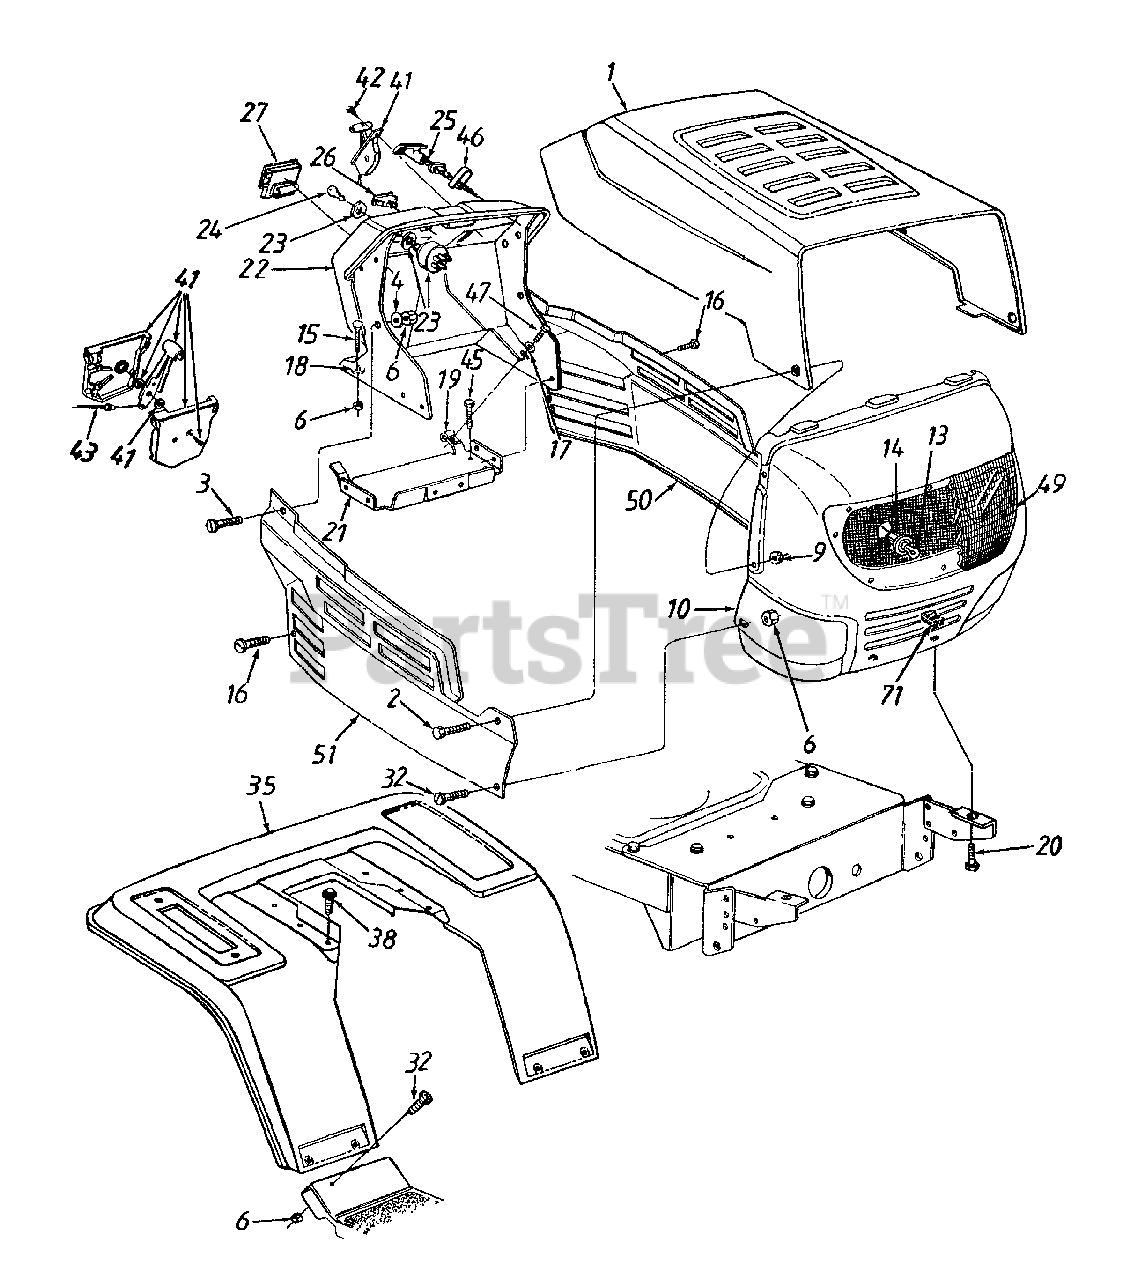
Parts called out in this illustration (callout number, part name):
1	Hood
2	Shld. Bolt .375" Dia. x .125" Lg.
3	Scr. 1/4-20 x .75
4	Wash. .283 x .030
6	Hex Sems Nut 1/4-20 Thd.
9	Flange L-Nut 1/4-20 Thd.
13	Lamp
14	Socket
15	Carriage Bolt 1/4-20 x .75" Lg.
16	Hex Wash. Hd. TT-Tap Scr. 1/4-20 x .5" Lg.
17	Fl-Wash. .281" I.D. x .73" O.D.
18	Bolt Retainer 1/4" I.D.
19	Speed Nut 1/4-20
20	Hex Bolt 5/16-18 x .75" Lg.
23	Ignition Switch
24	Ignition Key
25	Choke Control
26	Light Switch
27	Ammeter
32	Truss Mach. Scr. 1/4-20 x .5" Lg.
38	Hex Wash. Hd. AB-Tap Scr. 5/16 x .75" Lg.
41	Throttle Box Ass'y.
42	Truss Mach. AB-Tap Scr. #10 x .5" Lg.
43	Throttle Control Wire
45	Hex Wash. Hd. B-Tap Scr. 5/16-18 x .5" Lg.
46	Choke Retainer
47	Hex TT-Tap Scr. 1/4-20 x .75" Lg.
49	Lens
50	Side Panel - L.H.
51	Side Panel - R.H.
71	U-Nut 5/16-18 Thd.
